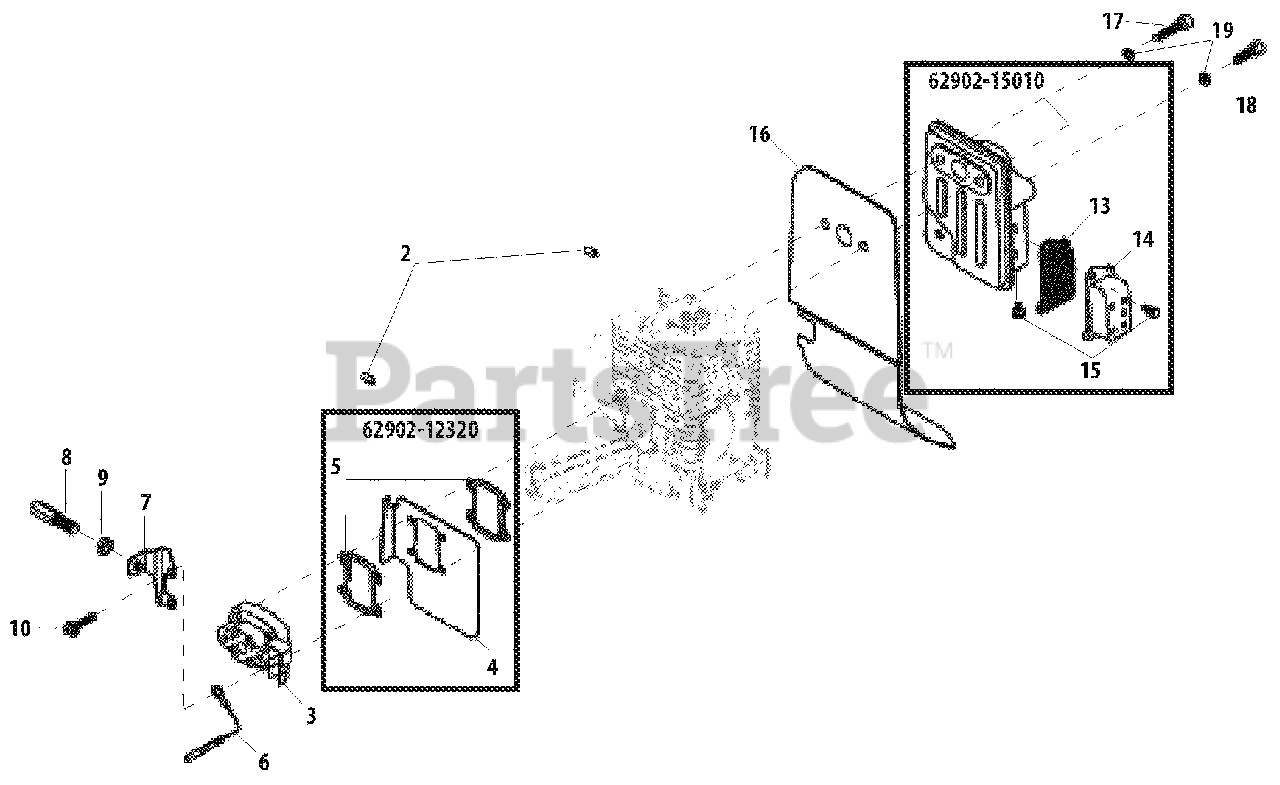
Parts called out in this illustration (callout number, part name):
2	PIN - LOCATING
3	INSULATOR
4	DEFLECTOR, HEAT
5	SHIELD, INTAKE
6	LEAD - GROUND
7	BRACKET, THROTTLE CABLE
8	NUT, CABLE ADJUST
9	LOCKNUT - 6
10	SCREW - 5X22
13	SCREEN, SPARK ARRESTOR
14	GUIDE, EXHAUST
15	SCREW - 4X6
16	SHIELD, EXHAUST
17	SCREW - 5X25
18	SCREW - 5X16
19	WASHER - 5
62902-12320	HEAT DEFLECTOR ASSY
62902-15010	MUFFLER ASSY
